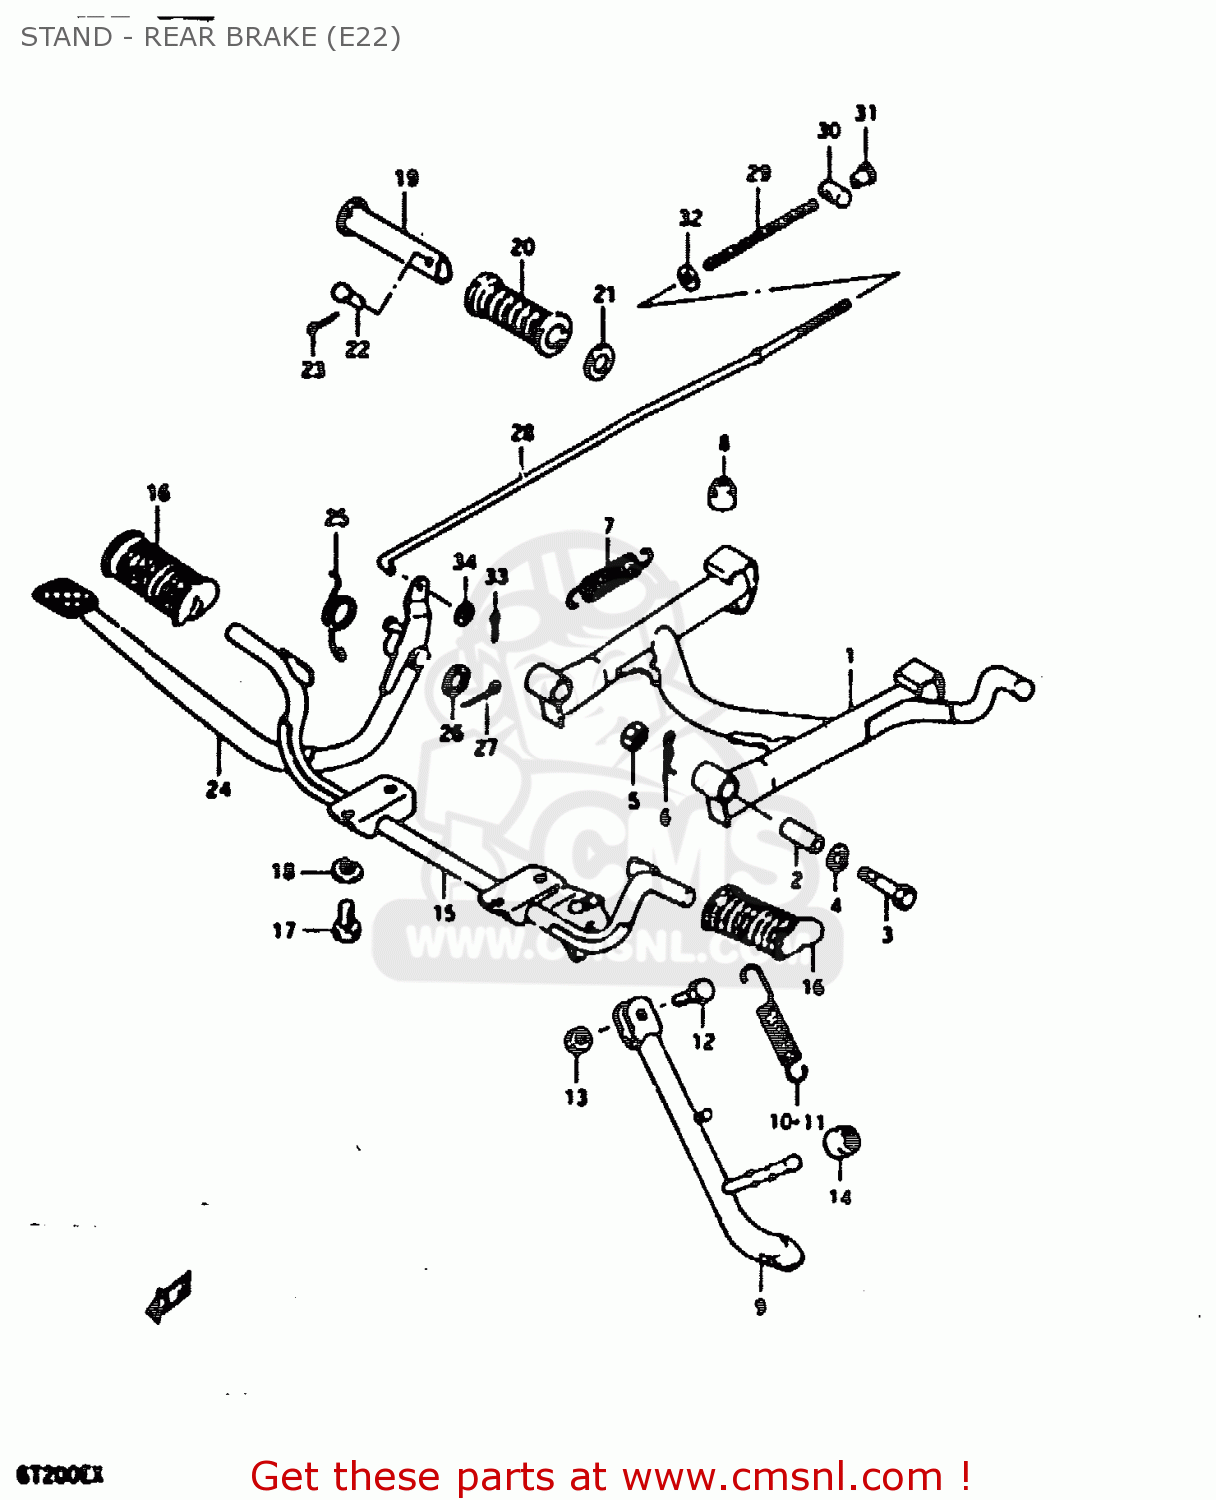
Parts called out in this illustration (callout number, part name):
1	STAND, CENTER
2	SPACER(10.5X16X30)
3	BOLT 10X52
4	LOCK WASHER
5	NUT
6	CLIP
7	SPRING
8	CUSHION
9	STAND, PROP
10	SPRING
11	SPRING, OUTER
12	BOLT
13	NUT
14	CUSHION
15	BAR, FRONT FOOTREST
16	RUBBER,FR FOOTREST
17	BOLT
18	LOCK WASHER
19	BAR,FOOTREST RUBBER
20	RUBBER,PILLION FOOTREST
21	WASHER (19.5X32X2)
22	PIN
23	PIN 20X20
24	PEDAL,BRAKE
25	SPRING
26	WASHER(15.5X26X2.3)
27	COTTER PIN
28	ROD ASSY, REAR BRAKE
29	SPRING
30	PIN
31	NUT
32	WASHER
33	PIN 20X20
34	WASHER
